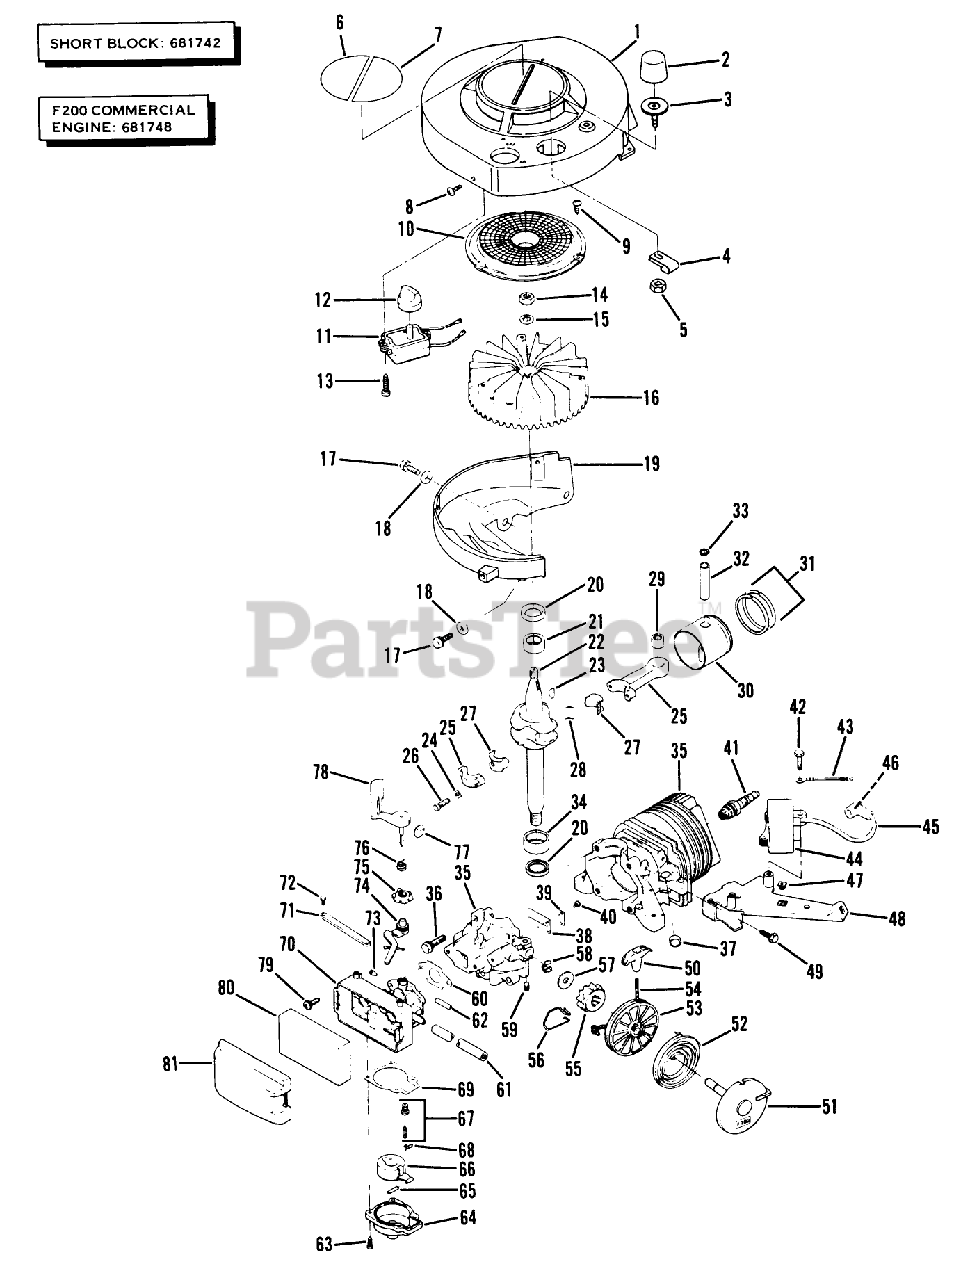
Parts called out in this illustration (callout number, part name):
5	LOCKNUT S
8	SCREW F
9	SCREW F
14	NUT
17	SCREW S
18	Washer
21	BEARING V
23	KEY
26	SCREW
27	LINER ASM
29	BEARING AY F
33	RING-RETAINING
34	BEARING V
36	SCREW S
37	PLUG-CORE VF
39	PLATE-BACKUP, REED
45	HT LEAD&COVER XEV
47	NUT-CLIP
50	HANDLE STARTER S
52	SPRING S
56	SPRING F
57	WASHER S
59	SET SCREW
60	GASKET CARB S
62	TUBING PRIMER S
63	SCREW-HH
73	F-SCREW CARB
74	LEVER
75	ADJUSTMENT COLLAR
76	SPRING
77	DISC S
79	SCREW
